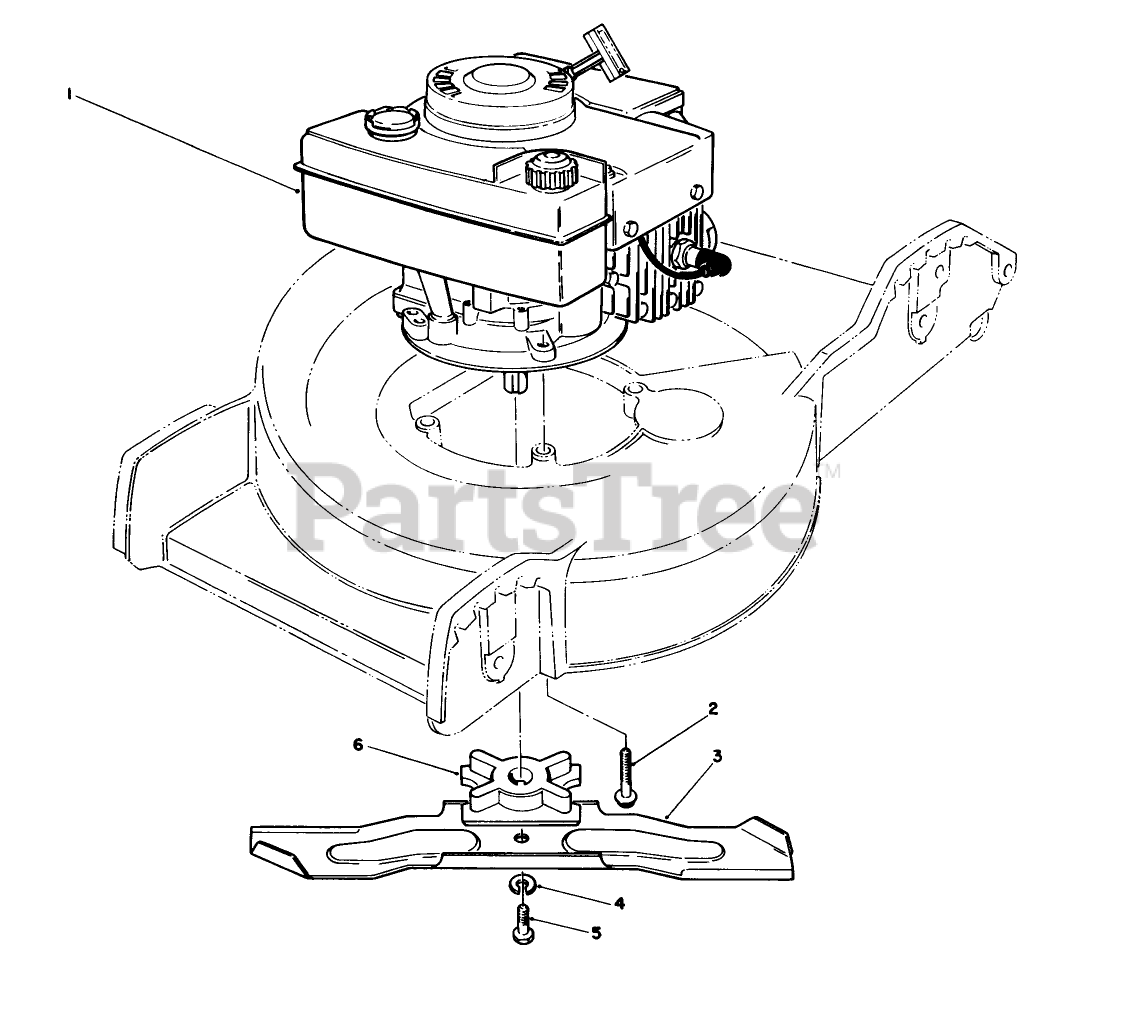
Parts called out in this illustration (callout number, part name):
2	3/8-16 X 2 CAPSCREW
3	Blade
4	WASHER-LOCK
5	SCREW-HH
6	BLADE RETAINER
